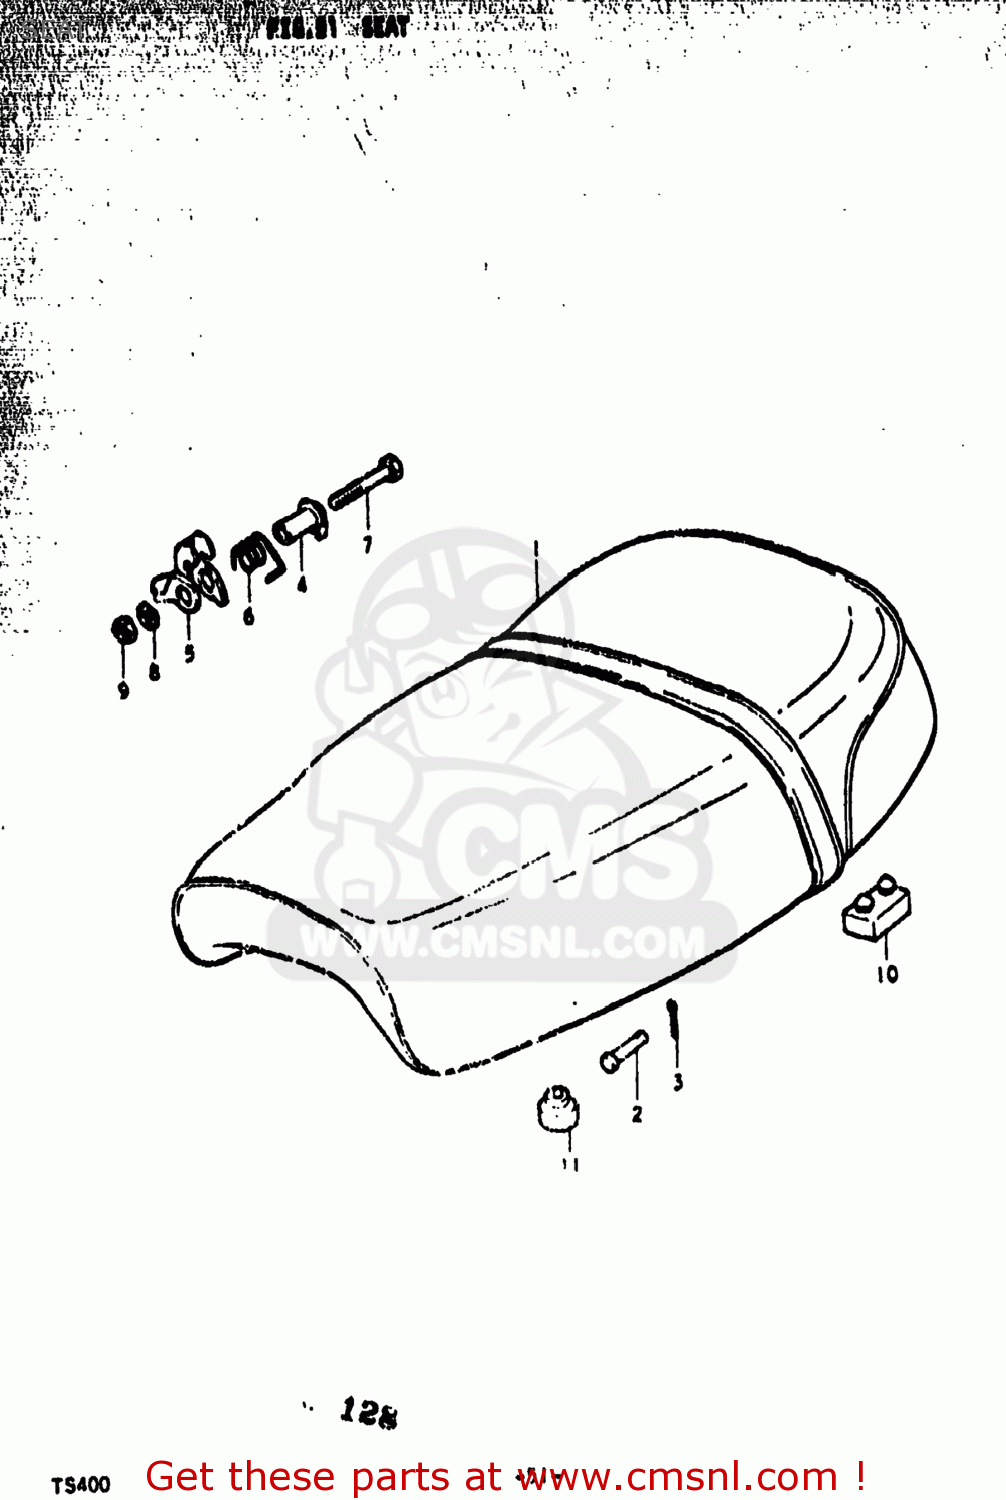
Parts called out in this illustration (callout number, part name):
1	SEAT ASSEMBLY
2	PIN
3	PIN
4	STRIKER,SEAT LOCK
5	STRIKER,SEAT LOCK
6	SPRING
7	BOLT 8X45
8	LOCK WASHER
9	NUT
10	CUSHION
11	CUSHION(11.5X22X20)
